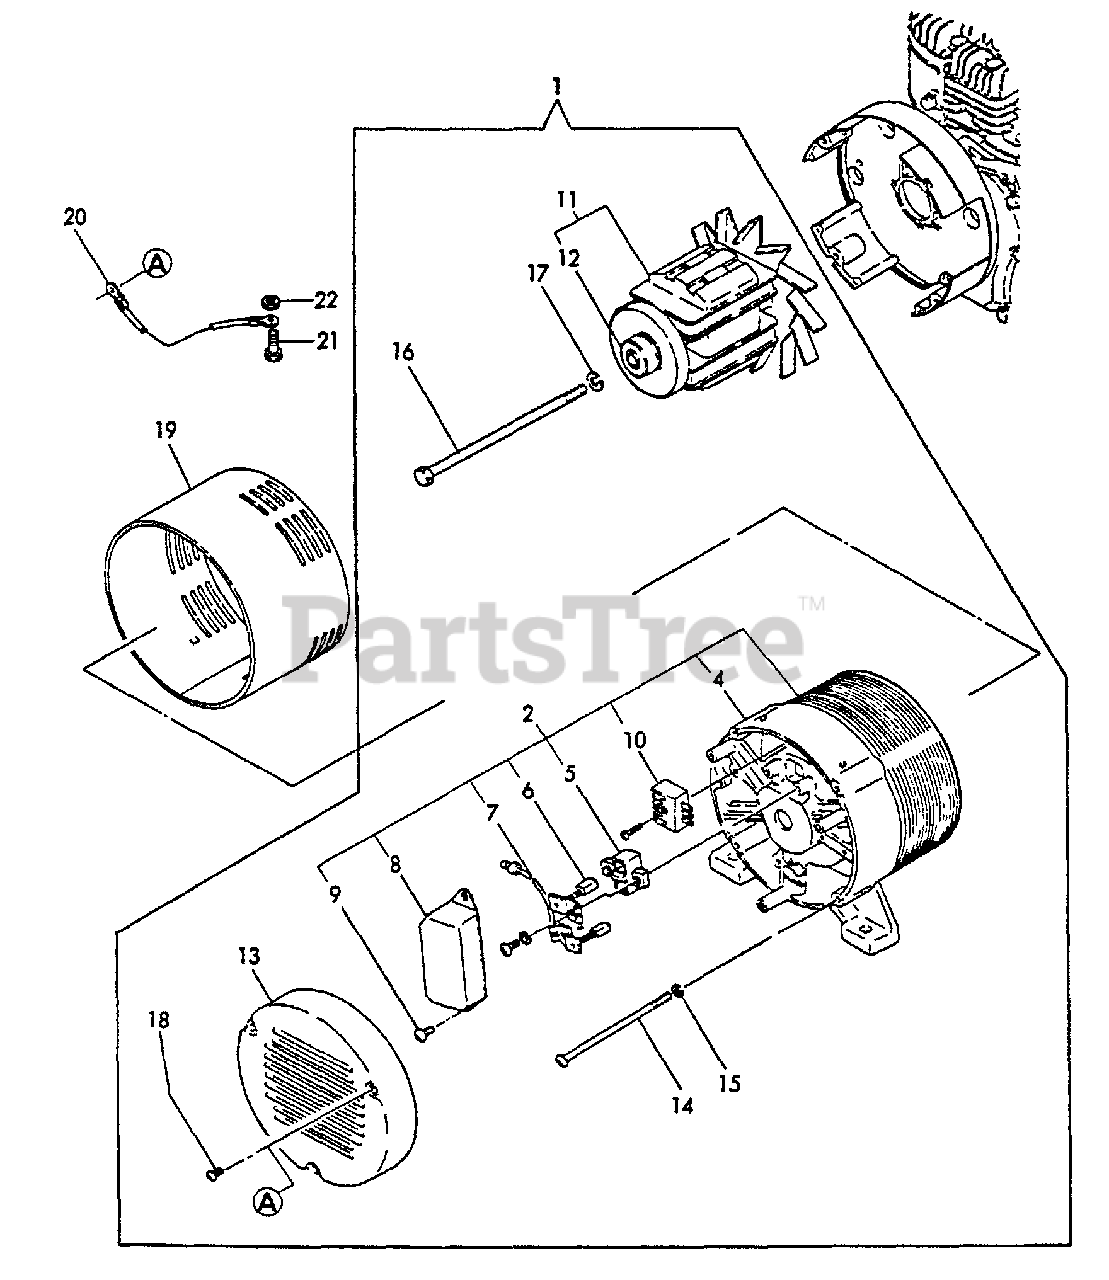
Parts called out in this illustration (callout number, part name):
1	GENERATOR 2.0 KVA
2	STATOR ASSY
4	COVER - REAR
5	HOLDER, BRUSH
6	BRUSH - ( + )
7	BRUSH - ( - )
8	A.V.R.
9	SCREW - 5X14
10	RECTIFIER
11	ROTOR ASSY
12	BEARING, BALL
13	COVER
14	BOLT, THROUGH
15	LOCKWASHER - 6
16	BOLT
17	LOCKWASHER - 8
18	SCREW - 4X8
19	BAND
20	LEAD - GROUND
21	BOLT - 6X16 -- PLATED
22	LOCKNUT - 6 -- PLATED
